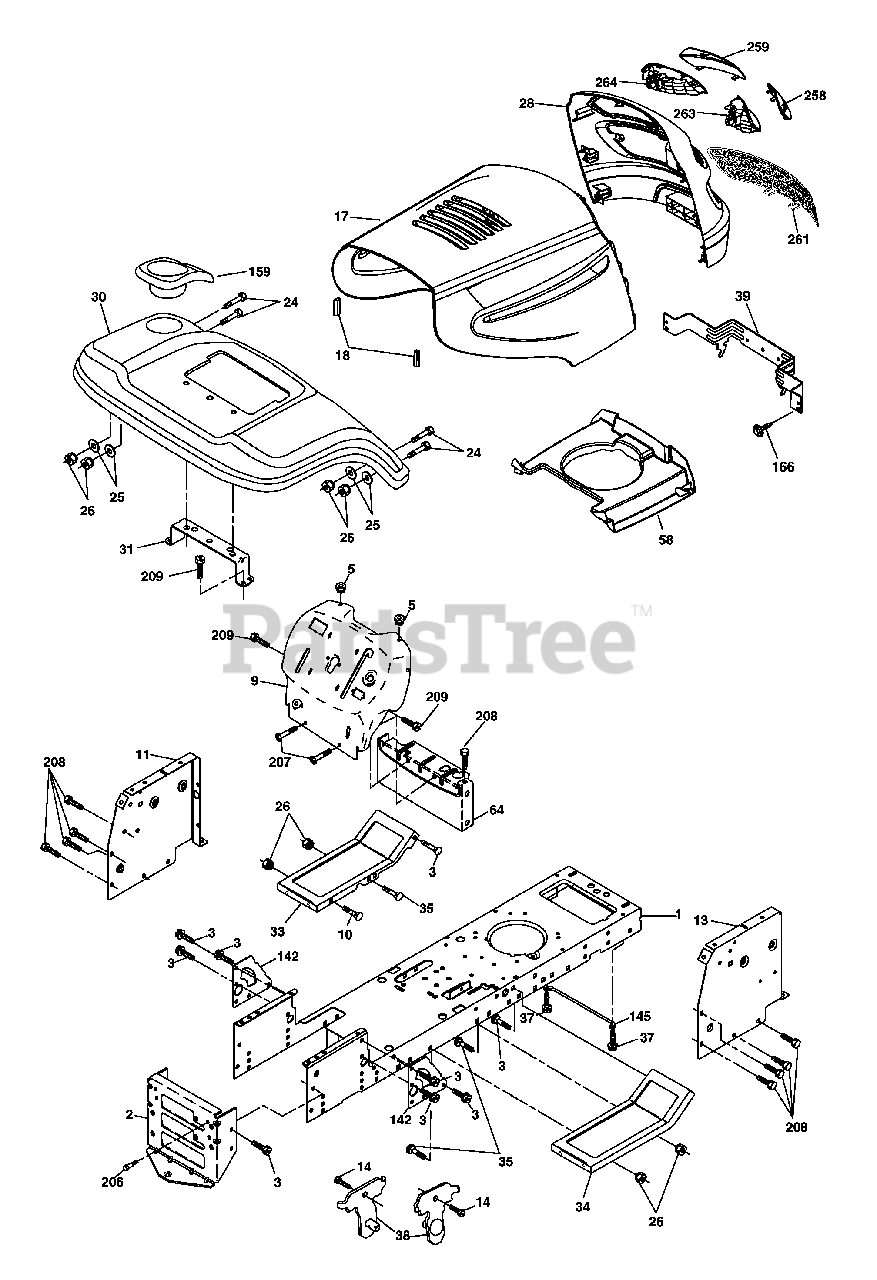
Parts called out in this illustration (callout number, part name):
1	Chassis
2	Drawbar
3	Screw 3/8-16 x 3/4
5	Bumper Hood/Dash
9	Dash
10	Bolt Rd Hd Sqnk. 3/8-16 Unc x 1
11	Panel Asm. Dash Lh
12	Clip Tinnerman Grile P/L
13	Panel Dash Rh
14	Screw Thdrol 3/8-16 x 1/2
17	Hood
18	Bumper Hood
24	Bolt Fin Hex 3/8-16 Unc x 1 Gr. 5
25	Washer 13/32 x 13/16 x 12 Ga.
26	Nut Lock Hex w/Insert 3/8-16 Unc
28	Grill/Lens Asm
30	Fender Asm
31	Bracket Fender
33	Footrest LH
34	Footrest RH
35	Bolt Rd Hd Sht. Sqnk. 3/8-16 x 3/4
37	Screw Thdrol 5/16-18 x 1/2 Tyt
38	Bracket Asm. Pivot Mower Rear
39	Bracket Pivot
58	Air Duct
64	Dash Lower
142	Plate Reinforcement
145	Rod Pivot Chassis/Hood
159	Cupholder
166	Screw #13-16 x 3/4
206	Bolt shoulder 5/16-18
207	Screw Thdrol 5/16-18 x 1/2
208	Screw Thdrol 3/8-16 x 1/2
209	Screw 3/8-16 x 3/4
258	Lens Grille RH
259	Lens Grille LH
263	Bezel Grille LH
264	Bezel Grille RH
